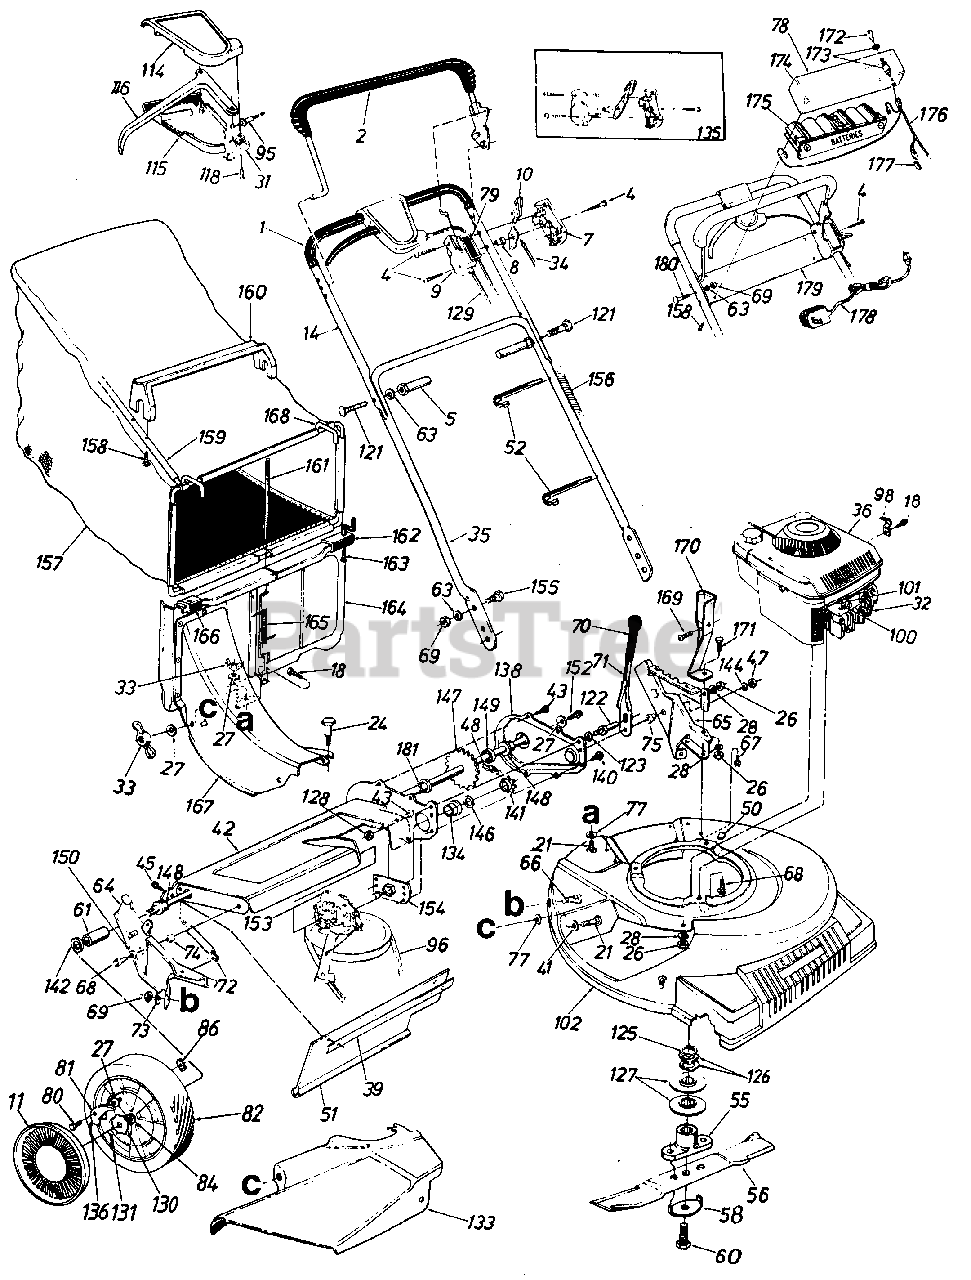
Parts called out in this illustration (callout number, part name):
2	Control Handle Ass'y. L.H.
4	Truss Mach. Scr. #12 x 1.50" Lg.
5	Catcher Support Pin
7	Control Panel Half
8	Control Disc Pin
9	Clutch Panel Half
10	Throttle Control Lever
11	Hub Cap
14	Upper Handle Chrome
18	Hex B-Tap Scr #10 x .38"
21	Carriage Bolt 1/4-20 x .62"
24	Shoulder Bolt .312 Dia. x .18 Lg. Special
26	Hex Nut 1/4-20 Thd.
27	Bell-Wash. 1/4" I.D.
28	L-Wash. 1/4" I.D.
31	S.P. Control Cover
32	Spark Plug Insulator
33	Wing Nut
34	Throttle Control Wire 58"
35	Lower Handle Chrome
36	Engine
39	Retaining Strip
41	Fl-Wash. .344" I.D. x .62"
42	Chain Axle Ass'y.
43	Hex B-Tap Scr. 1/4" x .38"
45	Hex AB-Tap Scr. 1/4 x .62"
47	Hex Patch L-Nut 3/8-24 Thd.
48	#48 Chain .500" Pitch x .30 Links
51	Rear Flap 3.75" x 17.30" Lg.
52	Cable Tie
55	Blade Adapter Kit
56	21" Blade
58	Blade Bell-Wash. .45" I.D.
60	Hex Bolt 7/16-20 x 1.5"
61	Spacer.513" I.D.
63	L-Wash. 5/16" I.D.
64	R.H. Handle Wheel Brkt. Ass'y.
65	L.H. Handle Wheel Brkt. Ass'y.
66	Carriage Bolt 5/16-18 x .62"
67	Hex Wash. Hd. B-Tap Scr. 5/1 6-1 8
68	Hex Wash. Hd. TT-Tap Scr. 3/8-1 6
69	Hex Nut 5/16-18 Thd.
71	Height Adj. Lever
72	Extension Spring 3.80" Lg.
73	Bell-Wash. 5/16" I.D.
74	Spacer.385" I.D.
75	Shld. Spacer .5" Dia.
77	Bolt Retainer 1/4 x .50" O.D.
78	Instruction Label
79	Control Label
80	Shld. Scr. .342" Dia. x .268
81	Pawl
82	Wheel Ass'y. Comp. Rear
84	Sleeve Bearing 1/2" I.D.
86	Flat Nut 1/4-20 Thd.
95	S.P. Cable x 50" Lg.
96	"V"-Belt
98	Casing Clamp
100	Hex B-Tap Scr. #10 x .62"
101	Casing Clamp
115	Self-Propelled Control Cover
116	Control Lever
118	Fl-"C"-Sunk Hd. Tap Scr. #10 x .75" Lg.
121	Curved Carr. Bolt 5/16-18 x 1.75" Lg.
122	Shld. Pin 1.43" Lg.
123	L-Wash. 3/8" I.D.
125	Serrated Wash. 1.0" I.D.
126	Wave Wash. 1.005" I.D.
127	Serrated Pulley Half
128	Hex Nut 3/8-24 Thd.
129	Control Cable 46"
130	Ratchet Wheel 1.62" O.D.
131	Cotter Pin 1/8" Dia. x 1"
133	Side Chute Deflector Ass'y.
134	Flange Bearing
135	Kit Control Housing Comp.
136	Spring Nylon
138	Chain Cover
140	Hex Wash. S-Tap Scr. 1/4-20 x.50" Lg.
141	Sprocket Shaft Ass'y.
142	Fl-Wash. .510" I.D. x 1.0"
144	Fl-Wash. .385" I.D. x .87"
146	Fl-Wash. 3/8" I.D.
147	Rear Shaft Ass'y. 21.94" Lg.
148	Hex Flange Brg. .506" I.D.
149	Fl-Wash. .531" I.D. x .930"
150	Fl-Wash. 3/8" I.D.
152	Hex Bolt 1/4-20 x .62" Lg. (Grade 5)
153	Transmission Comp.
154	Hex Bearing Cup
155	Truss Mach. Scr. 5/16-18 x . 75 " Lg .
156	Plastic Tubing
157	Grass Bag
158	Hex AB-Tap Scr. #12 x 1.25" Lg.
161	Chute Rod .188" Dia.
162	Door Clip
163	Hex AB-Tap Scr. 1/4 x .75" Lg.
164	Chute Door
165	Torsion Spring
166	Panel Clip
167	Top Discharge Chute Ass'y.
168	Front Catcher Frame
169	Truss Mach. Scr. 1/4-20 x .50" Lg.
170	Grass Catcher Bracket
171	Hex Bolt 1/4-20 x .50" Lg.
172	Ignition Key
173	Ignition Switch
174	Battery Tray
175	Battery Pack
176	Wire Harness
177	Plug
178	Battery Charger
179	Lower Battery Tray
180	Curved Carr. Bolt 5/16-18 x 1.38" Lg.
181	Hex Flange Bearing .506" I.D.
